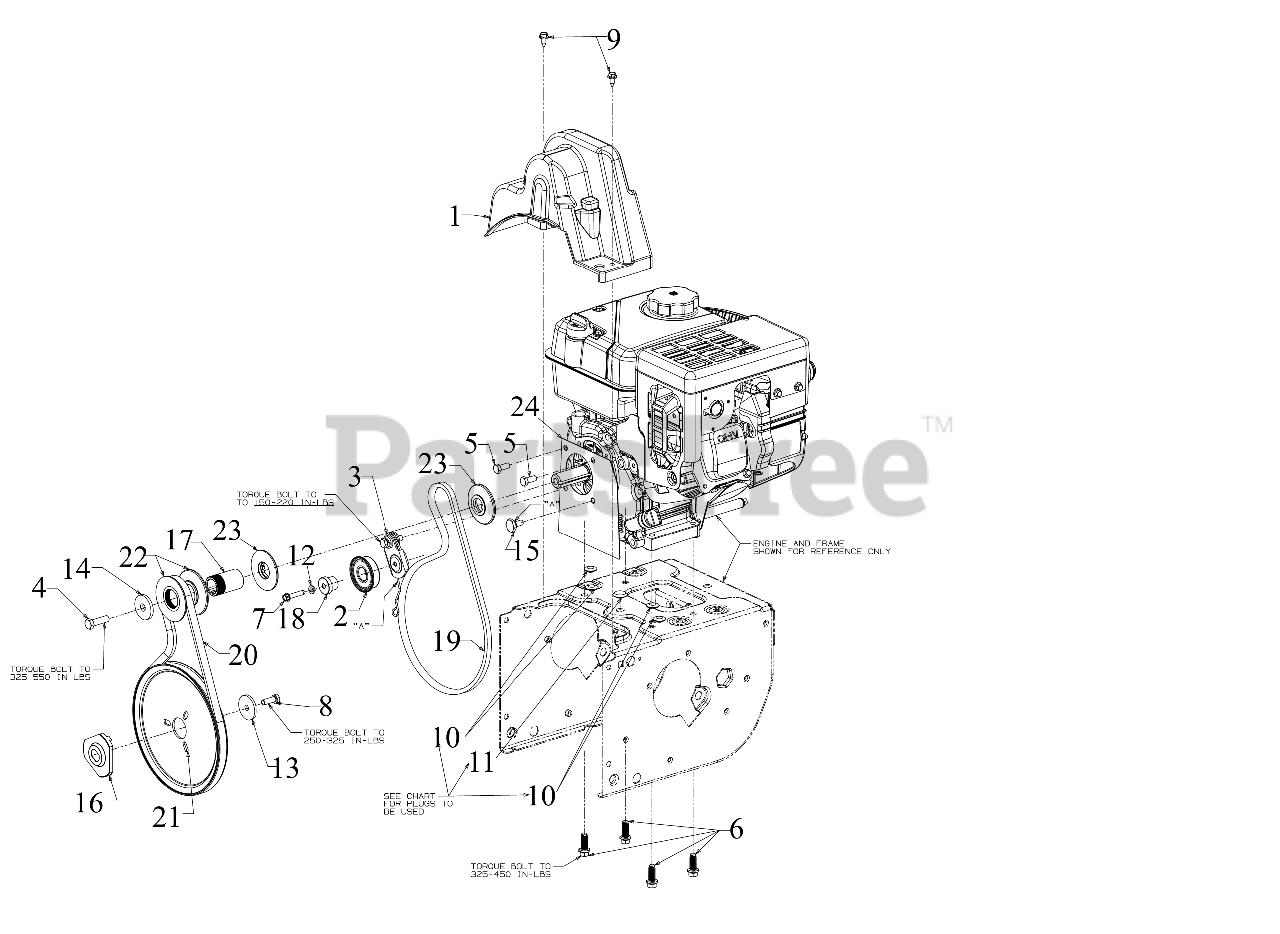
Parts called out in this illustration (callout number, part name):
1	BELT COVER (SMALL BLOCK)
2	IDLER PULLEY ASSEMBLY
3	Not Applicable
4	SCREW 3/8-24X1.25
5	SCREW 5/16-24 x .750 GR5
6	SCREW 3/8-16 x 1
7	SCREW 1/4-20 x 1.25
8	SCREW 5/16-24 x .875 GR5
9	SCREW 1/4-20X.625
10	PLUG-3/8 DIA ID x 3/32
11	PLUG-1/2 ID x 3/32
12	LOCK WASHER
13	FLAT WASHER
14	FLAT WASHER .45 x 1.5 x .172 HT
15	SHOULDER SCREW
16	ADAPTER PULLEY .75 DIA W/DD
17	PULLEY SPACER
18	SHOULDER SPACER
19	V-BELT 3/8 x 35
20	V-BELT .500 x 35.00LG
20	Cub Cadet AUGER BELT
20	Genuine Factory Parts AUGER BELT
21	AUGER PULLEY
22	HALF PULLEY 4L V x 2.6 OD
23	HALF PULLEY 3/8-V x 2.2
24	COVER PLATE
